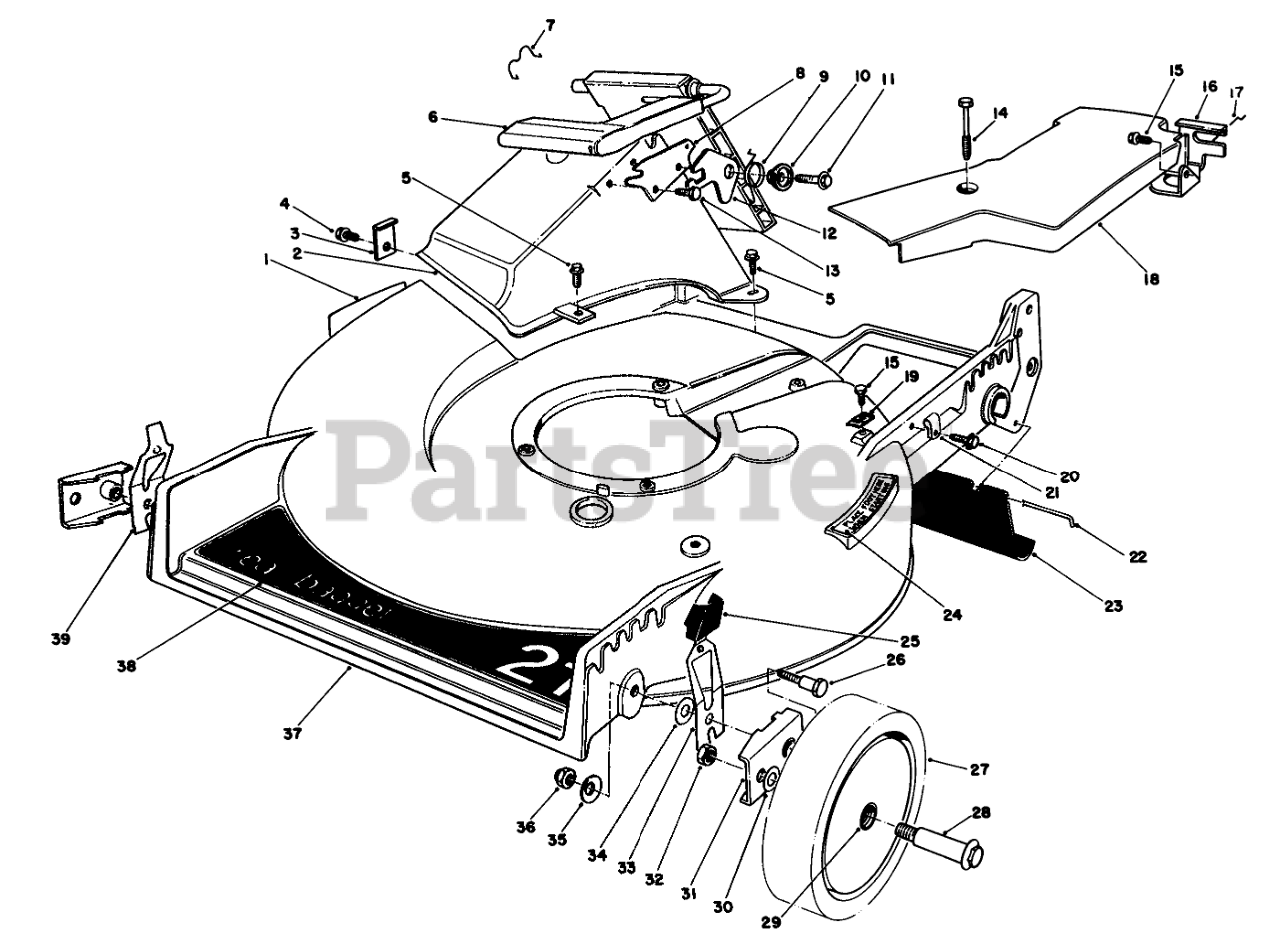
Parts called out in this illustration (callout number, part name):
1	DECAL-DANGER
2	Tunnel Discharge
3	TUNNEL CLIP
4	SCREW
5	SCREW-HWH
6	Discharge Door Assembly
7	DOOR RET SPRING
8	DOOR LATCH PLATE
9	TORSION SPRING
10	DOOR SPACER
11	SCREW-HWH
12	SAFETY LATCH
13	SCREW-PLASTITE
14	SCREW-HHFTF
15	SCREW-HWHTF
16	Bracket-Traction Adj.
17	RETAINER-CABLE
18	Cover-Belt
19	Cable Clamp
20	SCREW
21	CLAMP-CABLE
22	ROD-SHIELD
23	SHIELD-TRAILING
24	STEP PAD DECAL
25	KNOB-ARM
26	PIVOT SCREW
27	Wheel & Tire Assembly (Incl. Ref. #29)
28	WHEEL BOLT
29	BUSHING
30	WASHER
31	HP PIVOT ARM ASM
32	NUT-LOCK
33	L. HP SPRING ARM ASM
34	WASHER-PIVOT
35	WASHER
36	NUT-LOCK, NI
37	Housing-21" (Incl. Ref. #1, 5 & 24)
38	DECK DECAL
39	R HP SPRING ARM ASM
